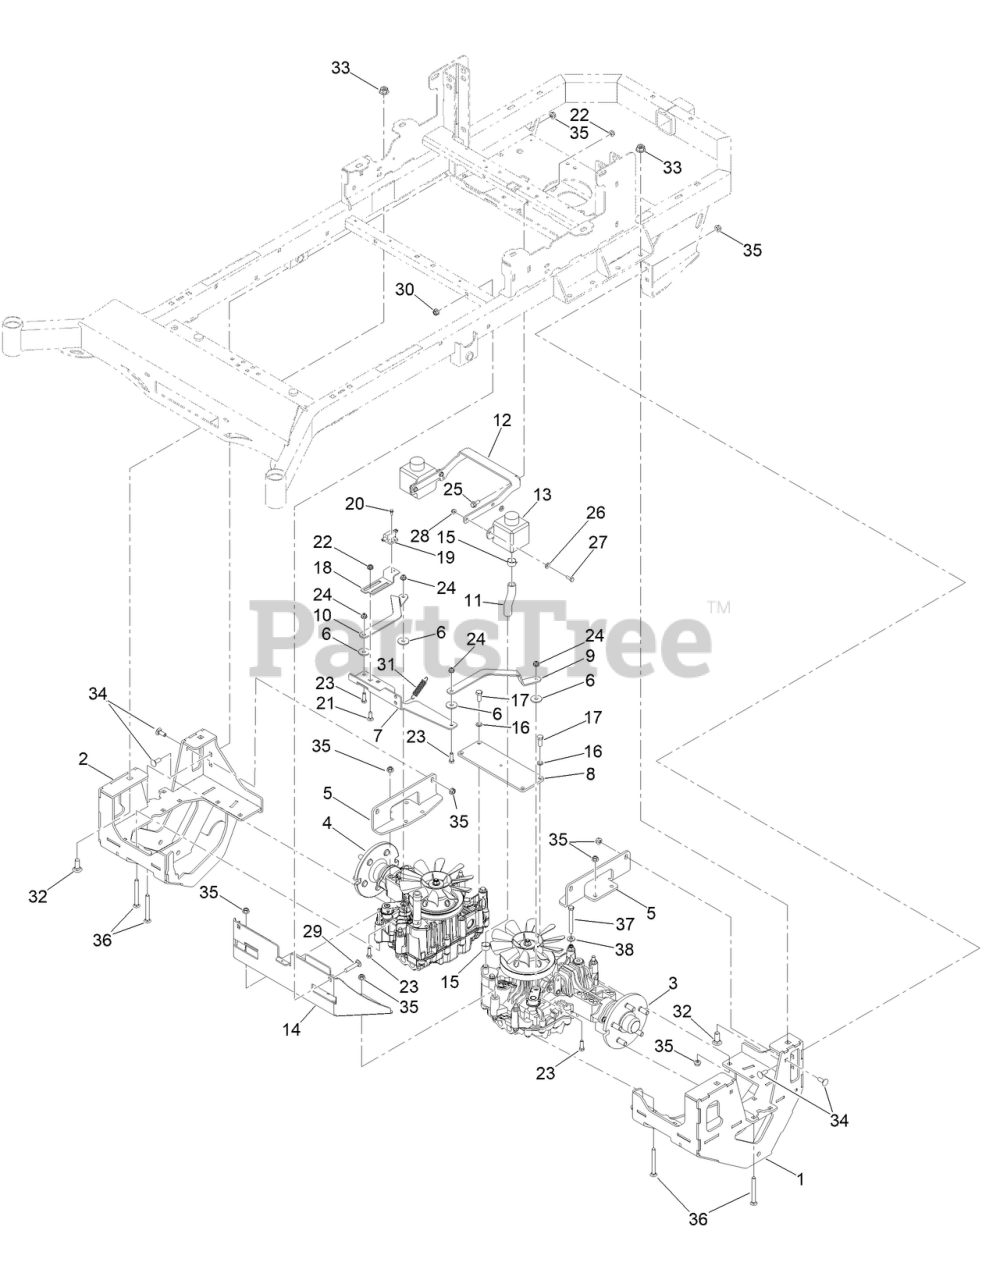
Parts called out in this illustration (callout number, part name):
1	HYDRO FRAME ASM, LH
2	HYDRO FRAME ASM, RH
3	2023 TZT-13 LT SIDE HYDRO TRANSMISSION
4	2023 TZT-13 RT SIDE HYDRO TRANSMN
5	BRACKET-SUPPORT, HYDRO
6	FLT WASHER 1.25ODX.38IDX.125 THK PLA
7	TT13 BRAKE ROD BRACKET
8	TT13 TRANSMISSION MOUNT BRACE
9	TT13 BRAKE ROD PLATE LEFT SIDE
10	TT13 BRAKE ROD PLATE RIGHT SIDE
11	MWR 5/8IN HYDRAULIC HOSE, 1FT
12	BRACKET-RESERVOIR
13	RT-PRO TT13 1/4 LITER HYDR FLUID RESRV
14	TT13 BATTERY BOX MOUNT PLATE PAINTED
15	22MM HOSE CLAMP (CTB-22ST-FK)
16	WASHER-LOCK
17	M10 X 1.5 X 25MM TAP BOLT
18	TT13 BRAKE INTERLOCK BRACKET: PAINTED
19	NO PLUNGER LIMIT SWITCH
20	8-32 X 1/2 IND. HWH SLOT TYPE F TCS ZINC
21	BOLT-CARR
23	SCREW-HH
24	NUT-HF, NI
25	SCREW-HHF
26	1/4 FLAT WASHER BLACK 18-8 BLACK ZINC
27	SCREW-HH
28	NUT-HF
29	SCREW-CARR
30	3/8-16 HEX FLANGE NUT W/SERR ZINC YELLOW
31	MWR BRAKE PEDAL RELEASE SPRING
32	SCREW-CARR,PATCH
33	1/2-13 HEX FLANGE 2-WAY REV CNTR L/NYZ
34	3/8-16 X 1 CARRIAGE BOLT YZ GR.8
36	SCREW-CARR
37	3/8IN-16X3-1/4IN HEX HD CAP SCR
38	WASHER-FLAT
